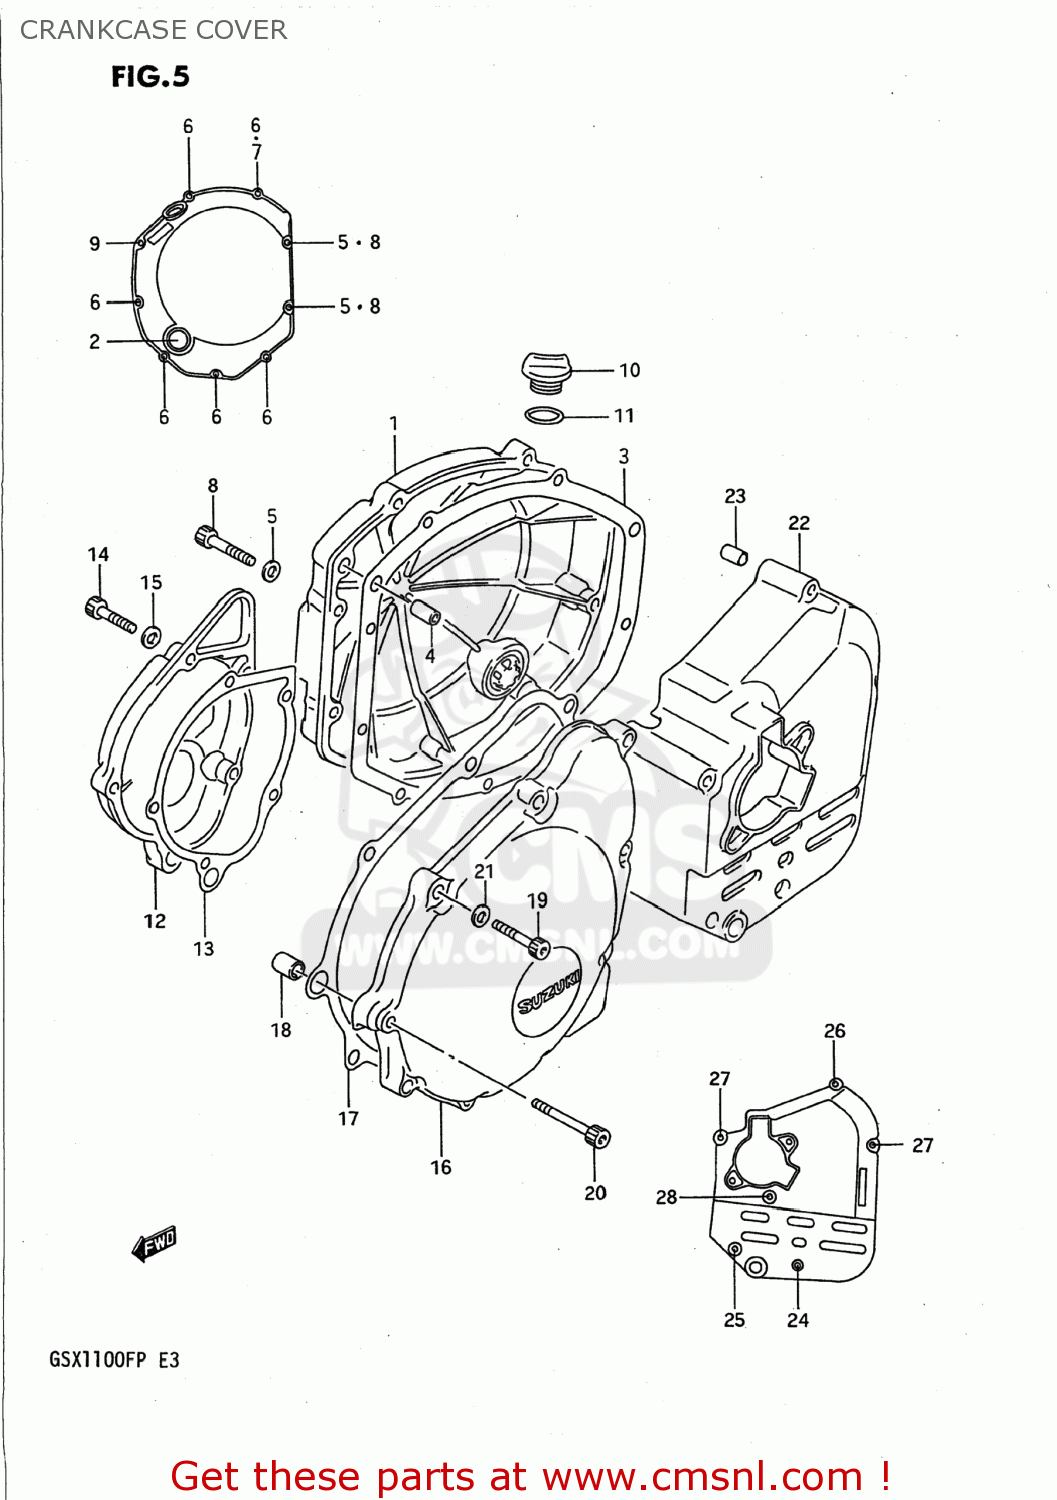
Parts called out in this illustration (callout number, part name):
1	COVER,CLUTCH
2	LENS,OIL LEVEL CHECK
3	GASKET,CL COVER (NAS)
4	PIN
5	GASKET(5.8X11X1.2) (NAS)
6	BOLT
7	BOLT
8	BOLT
9	BOLT
10	PLUG
11	O RING(D:3.1,ID:16.8)
12	COVER,CONTACT BREAKER
13	GASKET,SIGNAL GENERATOR COVER (NAS)
14	BOLT
15	GASKET(5.8X11X1.2) (NAS)
16	COVER,STARTER GEAR
17	GASKET,STARTER GEAR COVER (NAS)
18	PIN (11X20)(SUS)
19	BOLT
20	BOLT
21	GASKET(5.8X11X1.2) (NAS)
22	COVER,SPROCKET
23	PIN
24	BOLT
25	BOLT
26	BOLT
27	BOLT
28	BOLT
